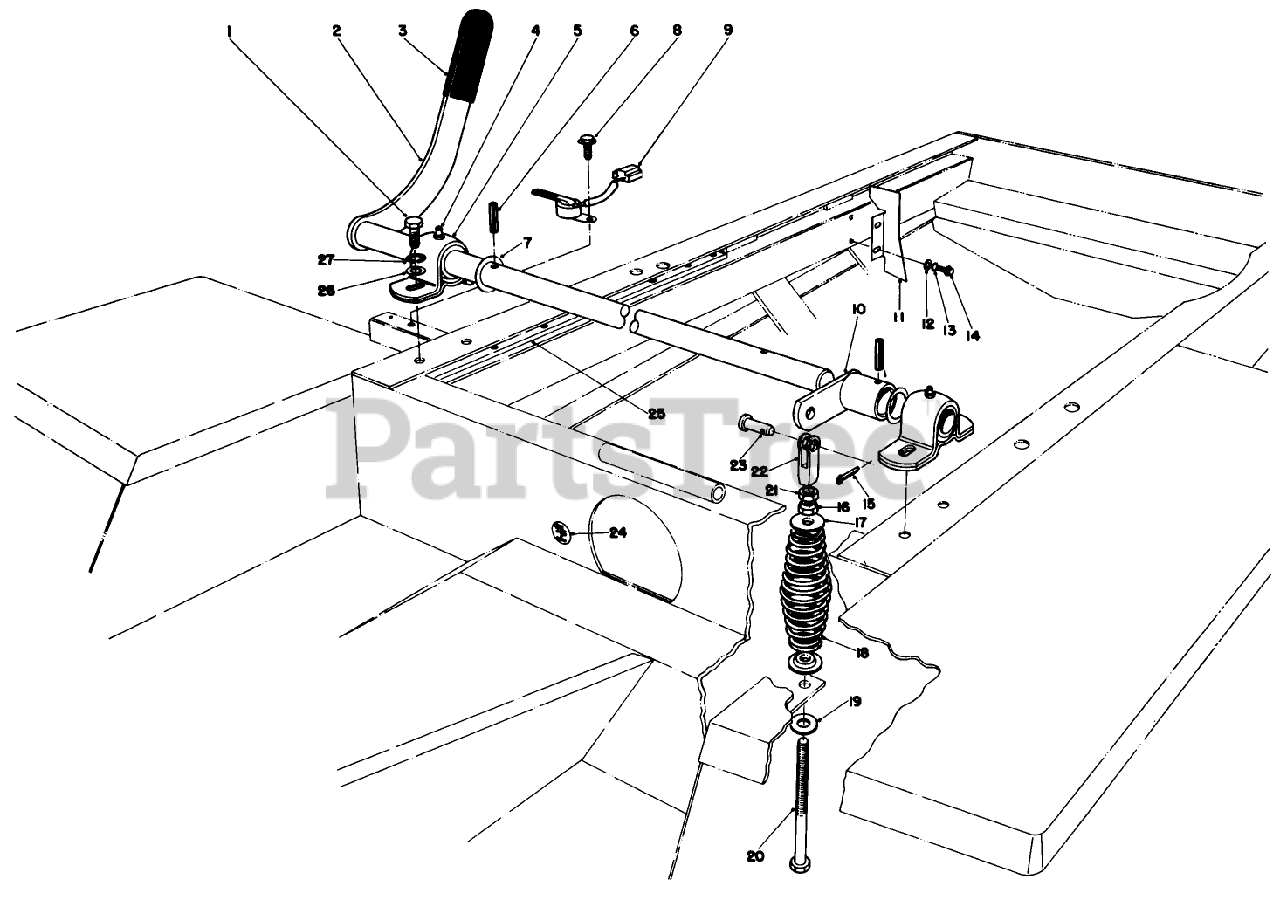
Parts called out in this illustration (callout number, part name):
1	SCREW-HH
3	GRIP-HANDLE
4	FITTING-GREASE
5	BEARING
6	PIN-SPRING
7	THRUST WASHER
8	SCREW-HWHTF
12	WASHER-PLAIN
13	SCREW-HH
15	SCREW-HH
16	NUT-HEX
17	SPRING RET TOP
19	WASHER
20	SCREW-ADJUSTING
21	NUT-HJ
23	PIN-CLEVIS
24	OIL DECAL
26	WASHER-FLAT
27	SCREW-HH
